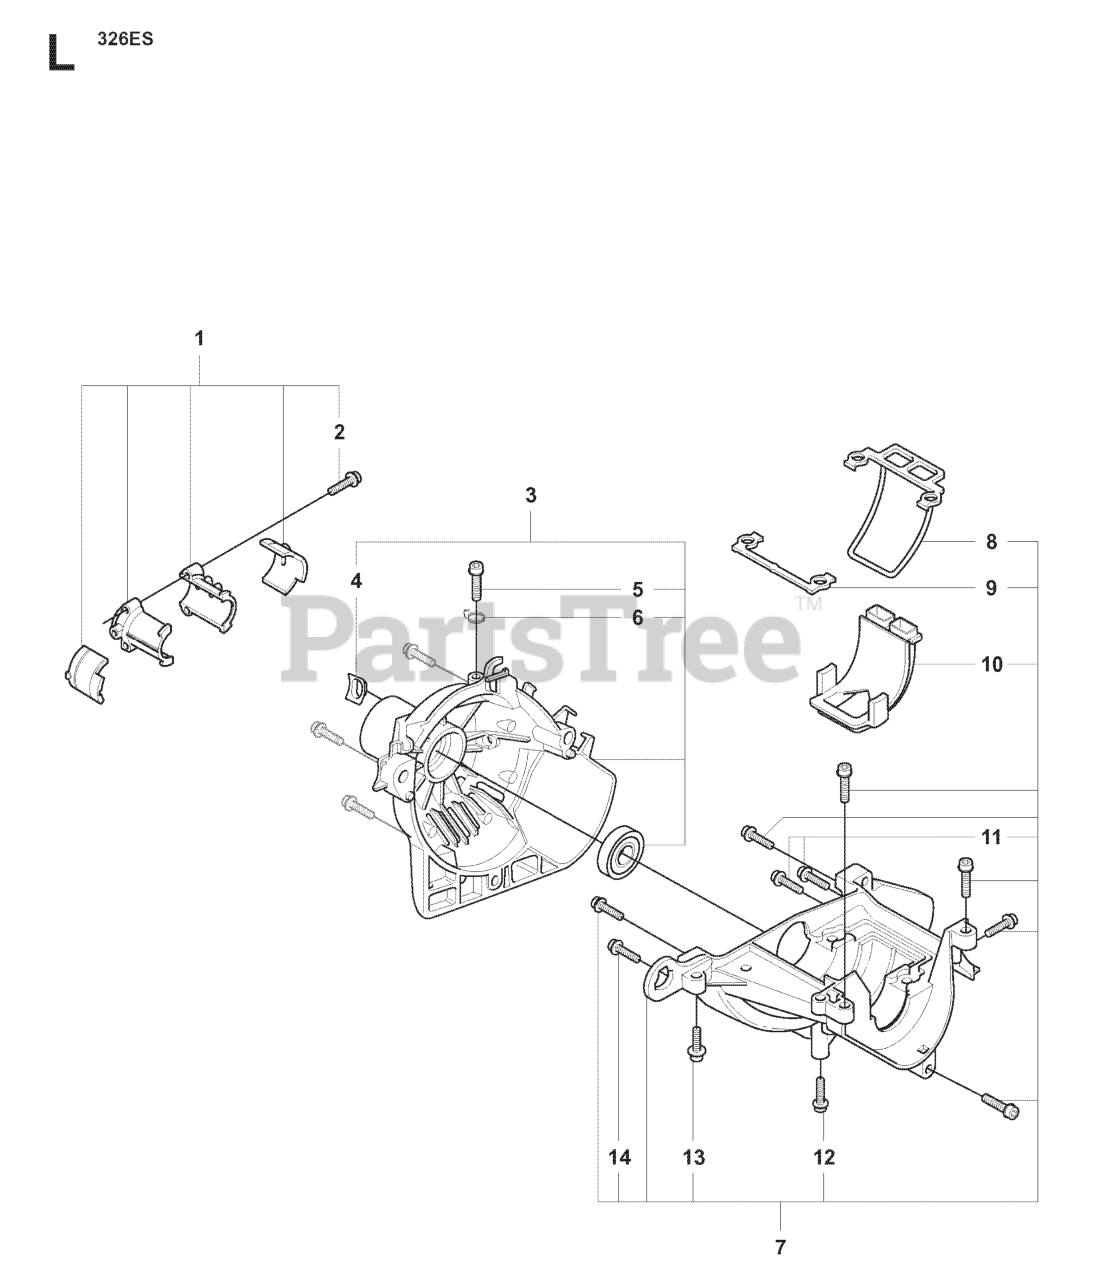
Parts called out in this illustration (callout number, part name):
1	COMPRESION SLEEVE/ISOLATOR SET
3	RP CLUTCH COVER
4	PROTECTION PLATE
7	CRANKCASE
